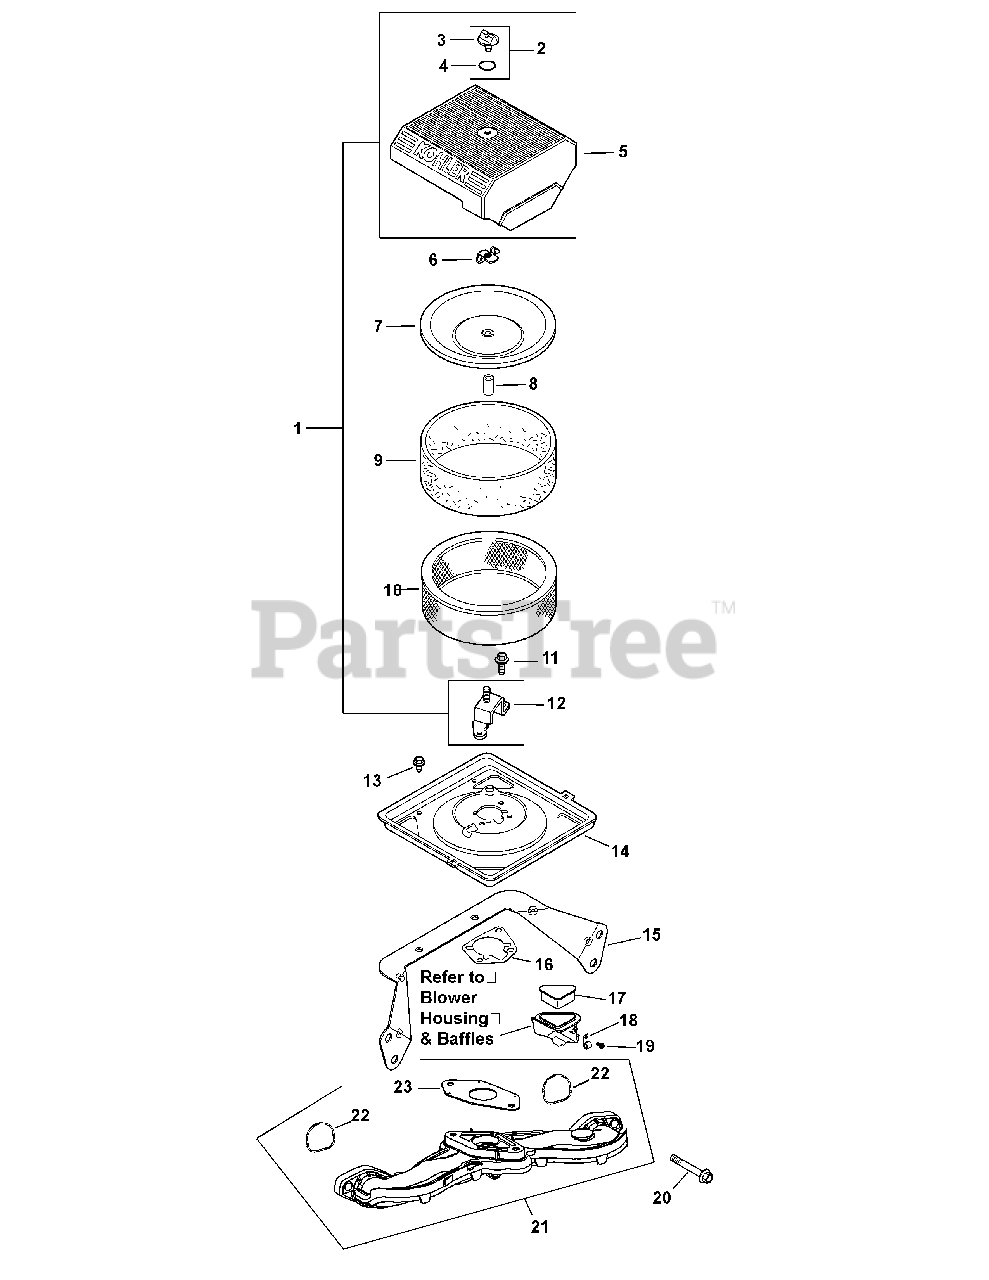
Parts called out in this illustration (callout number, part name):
1	Kit, air cleaner cover
2	Kit, knob w/seal
5	Cover, air cleaner
7	Cover, inner air cleaner
8	Seal, inner air cleaner
9	Element, precleaner
10	Element, air cleaner
11	Screw, flg thd frm M6x1.0x16
12	Bracket, air cleaner
13	Screw, flg thd frm M5x0.8x10
14	Base, air cleaner
15	Bracket, air cleaner base
16	Gasket, air cleaner base
17	Cover, blower housing
19	Screw, wsh hd tap #8-18x1/2"
20	Screw, flg M6x1.0x40
21	Manifold, intake - plastic
22	O-Ring, intake port
23	Gasket, carburetor
